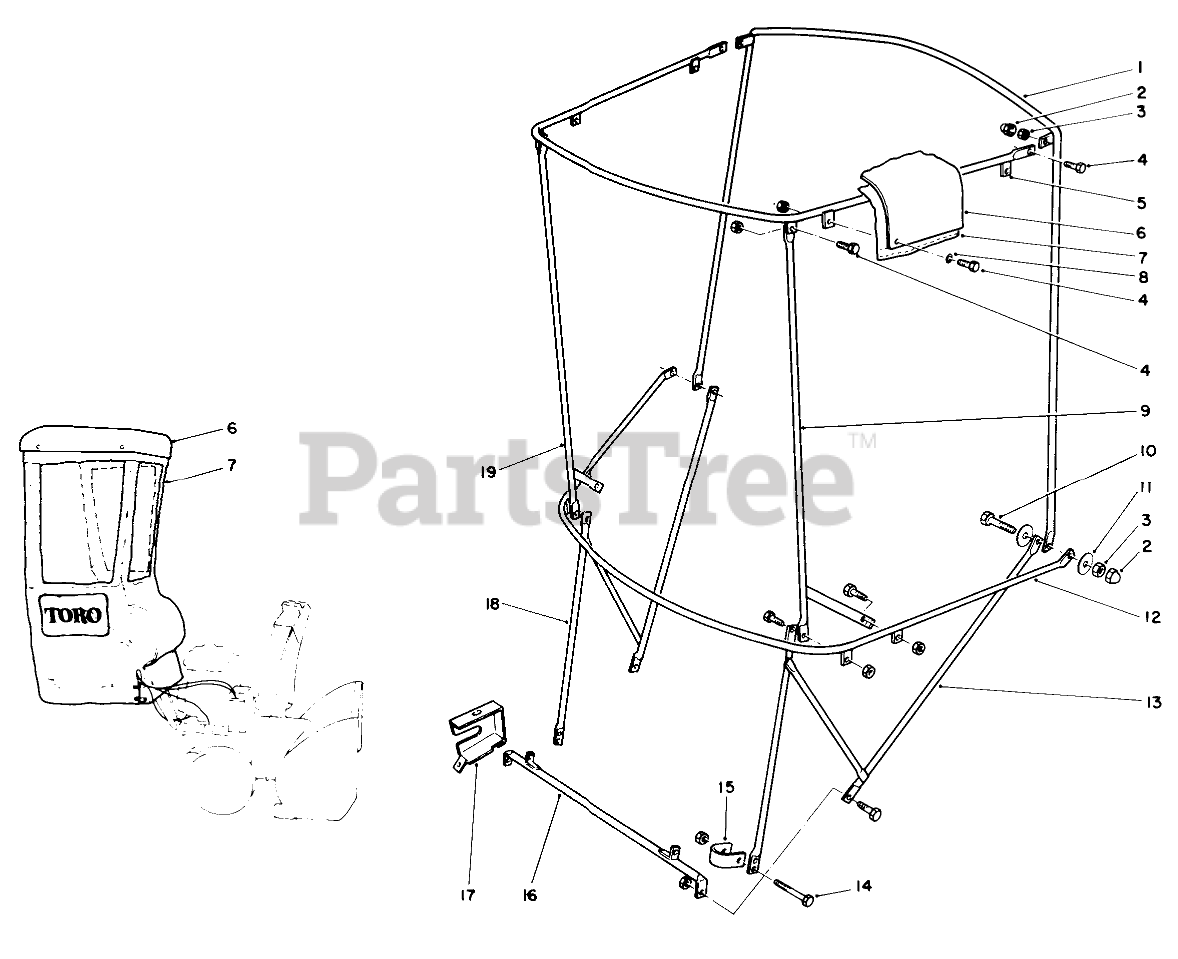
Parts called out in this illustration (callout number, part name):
1	VERTICAL BOW
2	CAPLUG
3	NUT-HEX, SIDE DEFORM
4	SCREW-HH
5	FRAME - TOP
6	Top-Plastic
7	Cover-Vinyl
8	WASHER-FLAT
9	CORNER POST - LH
10	SCREW-HH
11	WASHER-FLAT
12	HORIZONTAL BOW
13	Bracket-LH
14	SCREW-HH
15	CLAMP
16	Bracket-Base
17	COVER-LOCK, LEVER
18	BRACKET-RH
19	CORNER POST - RH
